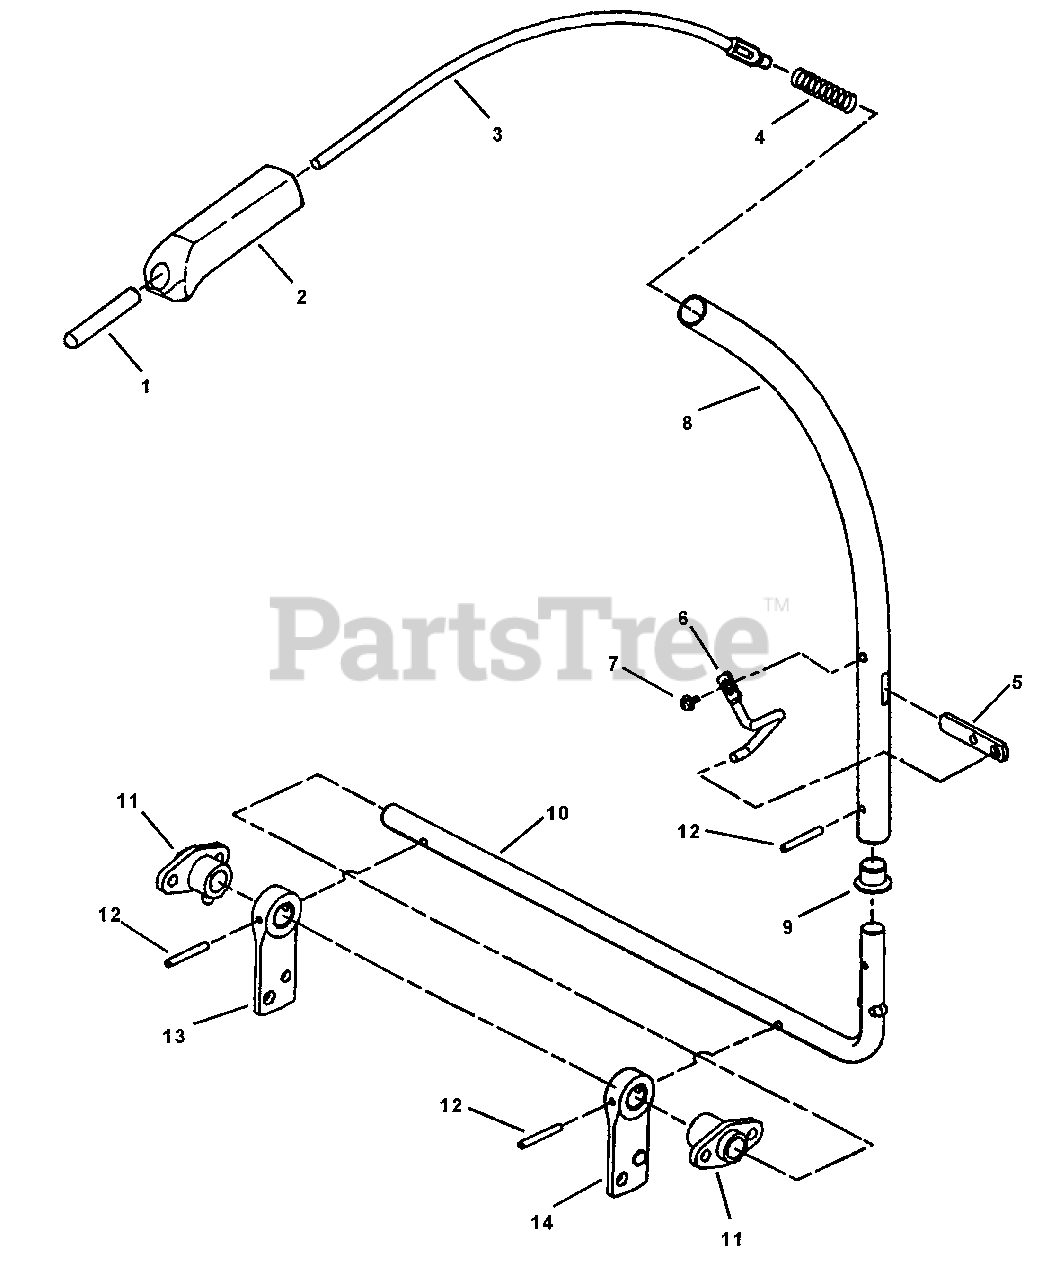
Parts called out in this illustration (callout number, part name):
1	GRIP, 5/16 x 2-1/2" Vinyl
2	GRIP, Brake/Clutch Handle
3	ROD, Park Brake
4	SPRING, Brake/Clutch Release
5	ARM, Brake/Clutch Lever
6	PIVOT, Brake/Clutch Lever
7	SCREW, 1/4-20 x 3/8" Hex Self-Tapping
8	TUBE, Brake/Clutch Lever
9	BUSHING, Nylon
10	ROD, Brake/Clutch
11	PIVOT, Foot Shaft Assembly
12	ROLL-PIN, 3/16 x 1-1/2"
13	ARM, Brake/Clutch
14	ARM, Brake/Clutch
